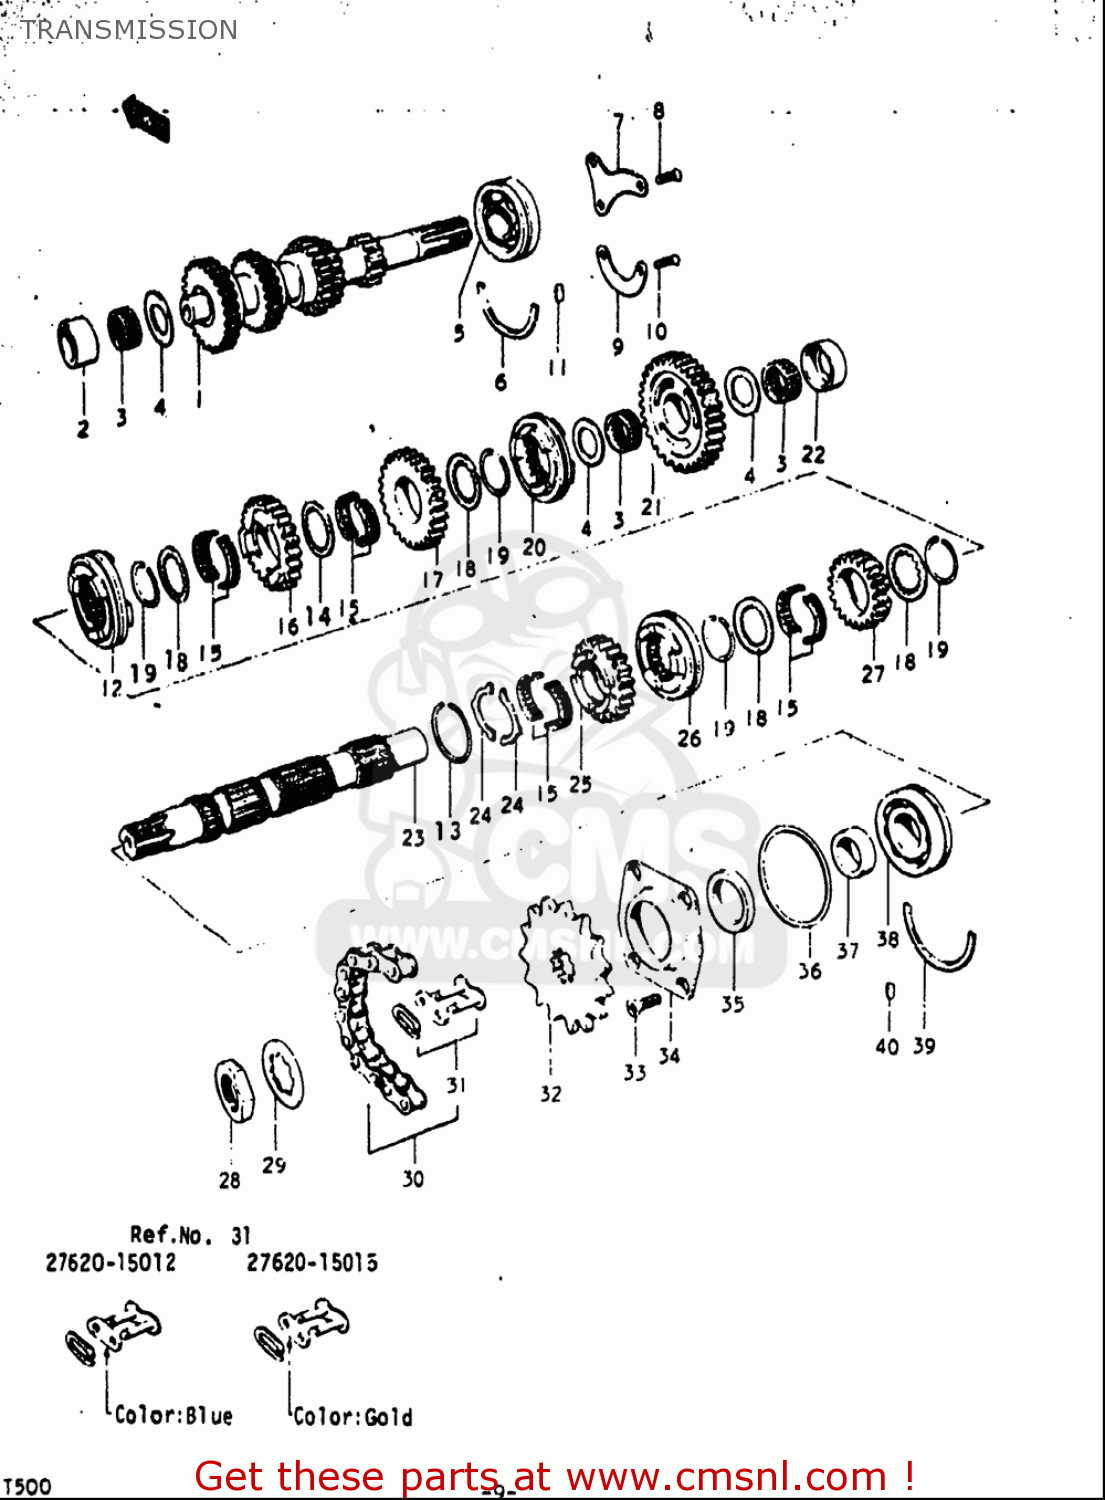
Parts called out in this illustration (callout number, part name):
2	BUSHING
4	WASHER (20X30X1)
6	C-RING
8	SCREW
10	SCREW
11	PIN
13	CIRCLIP
14	WASHER
15	ROLLER BEARING (NTN
16	GEAR,THIRD DRIVEN
18	WASHER
19	SPRING
22	BUSHING
24	KNOCK RING
28	NUT
29	WASHER,LOCK
32	SPROCKET,ENGINE
33	SCREW
35	SEAL,OIL(25.9X42X7)
36	O RING(D:1.9,ID:63.1)
37	SPACER (22X27X10.6)
38	BALL BEARING 22X59X.6
39	C-RING
40	PIN
